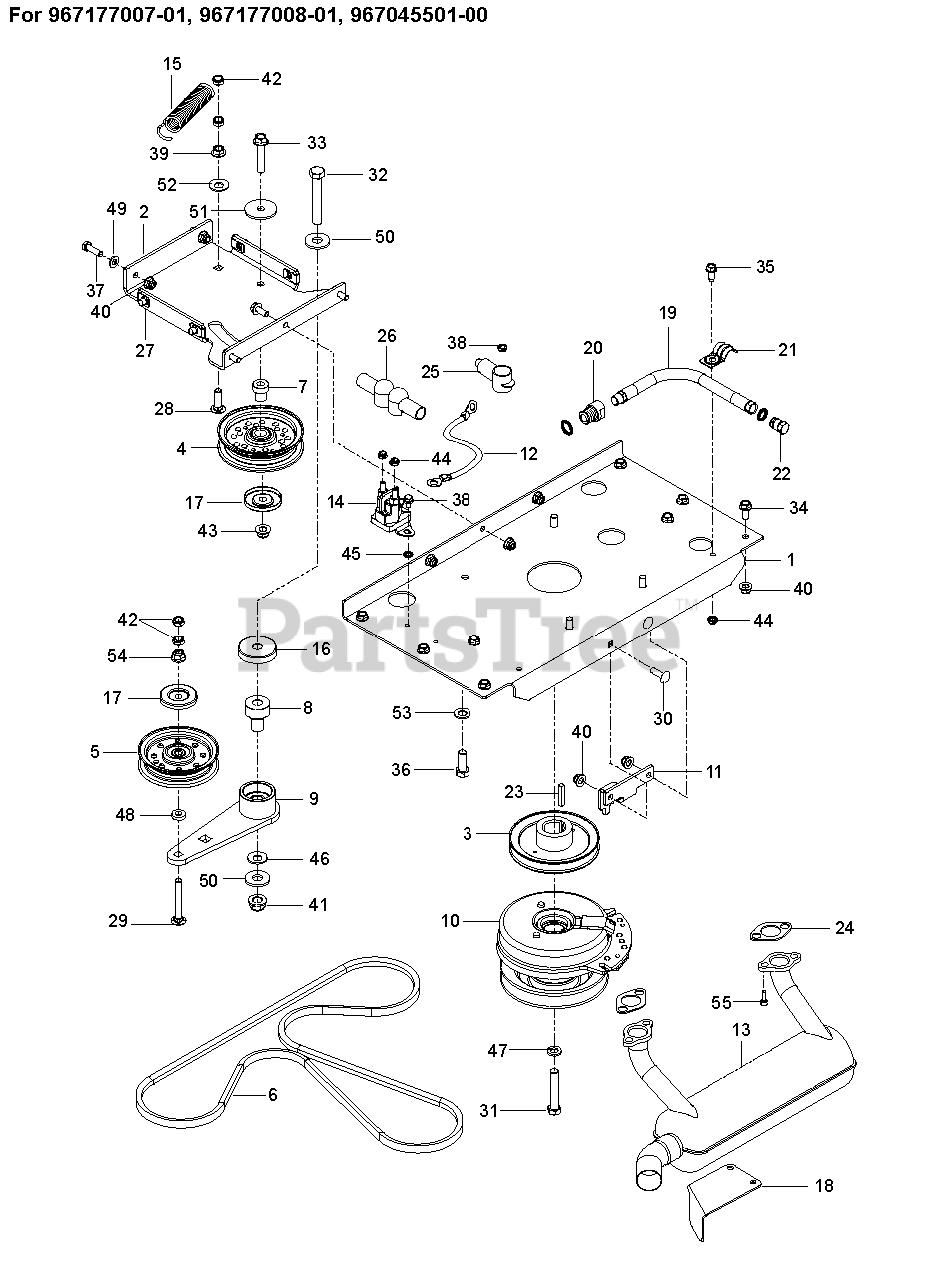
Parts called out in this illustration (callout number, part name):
1	PLATE.PNT.ENGINE.E-DIP
2	PLATE, IDLER, BLK
2	PLATE.PNT.IDLER.SUPPORT.E-DIP
3	PULLEY, V, 1.125 BORE
4	IDLER PULLEY
5	PULLEY.IDLER.FLAT.46.PR.DR.
6	BELT, HYDRO, 3400
7	PIVOT, IDLER
8	PIVOT, BEARING
9	ARM, IDLER, STEEL, W/BGS
10	CLUTCH 200 FT LB
11	STOP, CLUTCH, BLACK
12	CABLE POSITIVE
13	MUFFLER.26HP.KAW.FX651V-730V
13	MUFFLER, B&S CYCLONIC
13	MUFFLER ASY KOH.EFI.W/O2 SEN
14	SOLENOID.STARTER.BRASS.PLUNGER
15	SPRING, PUMP
16	SHIELD, DUST
17	DUST SHIELD
18	SHIELD MUFFLER
19	HOSE.ASSEMBLY.OIL.DRAIN
20	ADAPTER, OIL DRAIN
21	CLAMP
22	PLUG OIL DRAIN
22	PLUG, DRAIN 3/8 NPTF
23	KEY, 1/4 SQ X 1 1/4
24	GASKET.EXHAUST.KAWASAKI
25	INSULATOR
25	TERMINAL COVER
26	TERMINAL COVER
27	U-CLIP 5/16-18 NUT RETAINER
28	BOLT.3/8-14X1.25
28	RHSNB 3/8-16 X 1-1/4
29	RHSNB 3/8-16 X 2.75
29	BOLT
30	BOLT CRT
31	CLUTCH BOLT7/16-20X2.5 GR596HR
32	HCS 1/2C X 3 1/4
32	HCS 1/2-13 X 3-1/4 GD 5 ZD
33	HHFS 3/8-16 X 2.0 GD 5
34	HHFS 5/16-18 X 3/4
35	HCS 1/4-20.
35	BOLT
36	SCREW 3/8-16X1
36	HCS 3/8-16X1.GRD.5.ZD
37	HCS 5/16C X 1
37	BOLT.FIN.HEX.5/16-18UNC X 1.00
38	HWST 1/4C X 3/8
38	RP_SCREW.1/4-20X3/8
39	NUT 3/8C WHIZ
40	5/16-18 NYLOC FLANGE NUT
41	NUT, 1/2-13 HEX FLG NYLOC ZD
42	NUT HEX 3/8-16 NYLON, THIN
43	NUT 3/8-16 HEX FLG NYLOC ZD
44	JAM NUT 1/4C (2 2 PW01)
45	WASHER 1/4 INT TOOTH
46	CONTACT BELLSPR 1/2
47	WASHER 7/16 LOCK
48	WASHER 3/8 X 3/4 X .187 TK
49	FLAT WASHER 5/16 SAE
49	WASHER
50	WASHER.9/16 X 1 3/8 X 12 GA.
50	WASH USS FLAT 1/2
51	WASHER, 3/8 SPEC
52	RP WASHER 3/8 FLAT
53	SLW 3/8 STD
54	NUT 3/8C WHIZ
54	NUT 3/8-16 HEX FLG NYLOC ZD
55	SCREW.SOCKET HD.5/16-1
55	SCREW.SOCKET.HEAD.5/16-18
